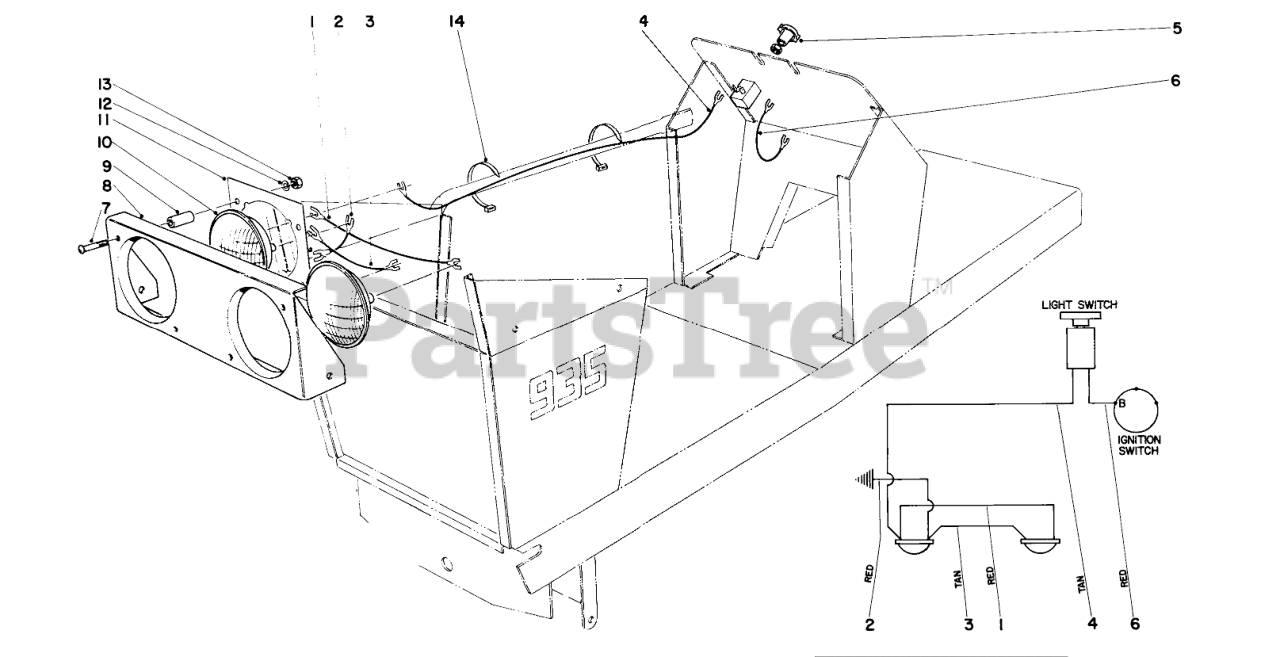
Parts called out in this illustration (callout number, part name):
1	Wire 960
2	Wire Assy.-Red
3	Wire 960
4	Wire Assy.
5	Light Switch
6	Wire Assy.-Red
7	Round Head Pan Screw
8	Headlamp Panel
9	Spacer
10	HEAD LAMP
11	Headlight Holder
12	WASHER-LOCK/SP
13	NUT-HEX
14	Cable Tie
